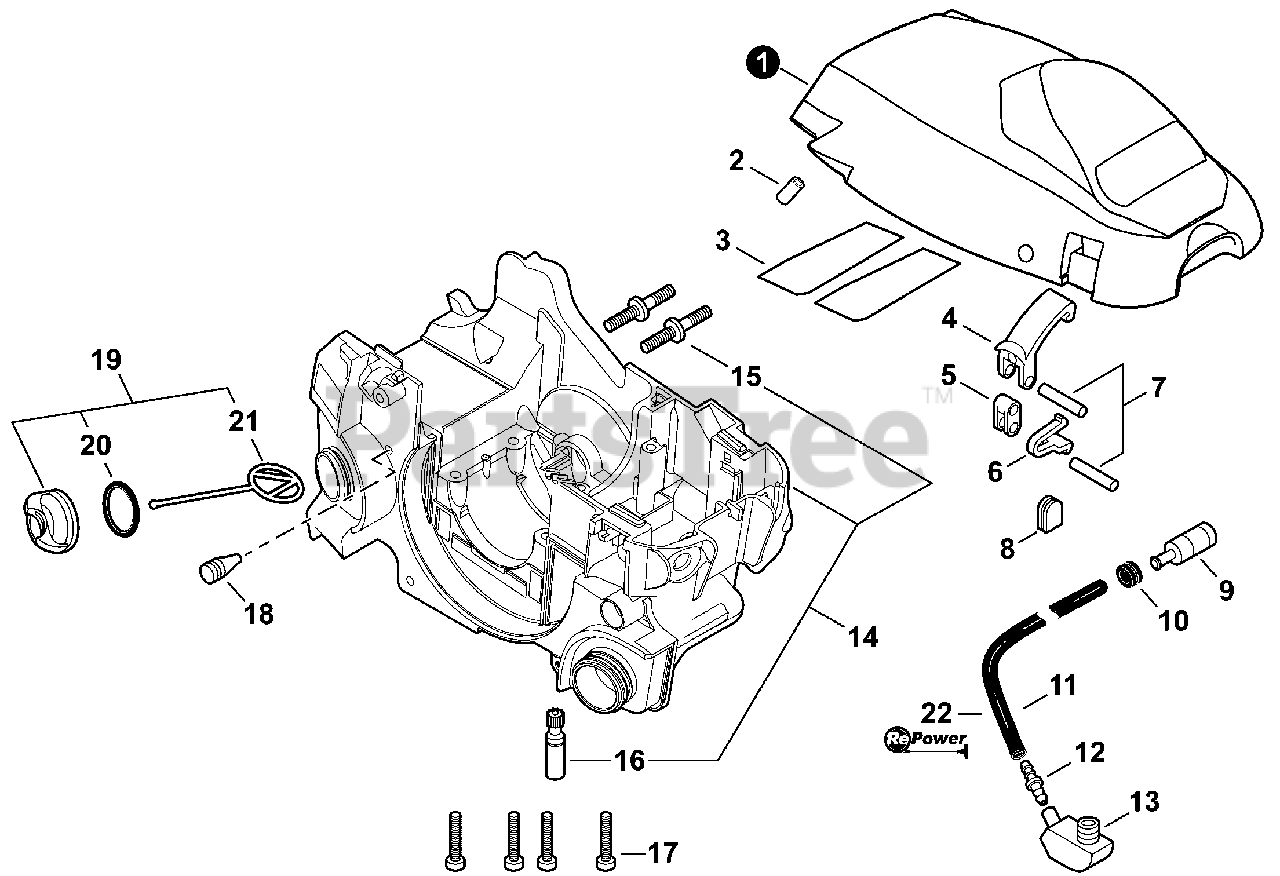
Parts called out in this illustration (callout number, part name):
1	COVER, ENGINE
2	BUSHING 3×7×10
3	SHIELD, HEAT
4	LATCH, ENGINE COVER
7	PIN 4×17.8
9	FILTER, OIL
10	GROMMET
11	PIPE 3×6×185mm BLACK
12	CONNECTOR, PIPE
13	GROMMET, OIL
14	HOUSING ASSY, ENGINE
15	BOLT, STUD 8
16	AUTO-OILER ASSY
17	BOLT, TORX 5×30
18	VENT ASSY
19	CAP ASSY, OIL
20	O-RING 18
21	CONNECTOR, CAP L= 60mm
22	PIPE, FUEL - REPOWER BULK 3×6mm BLACK
